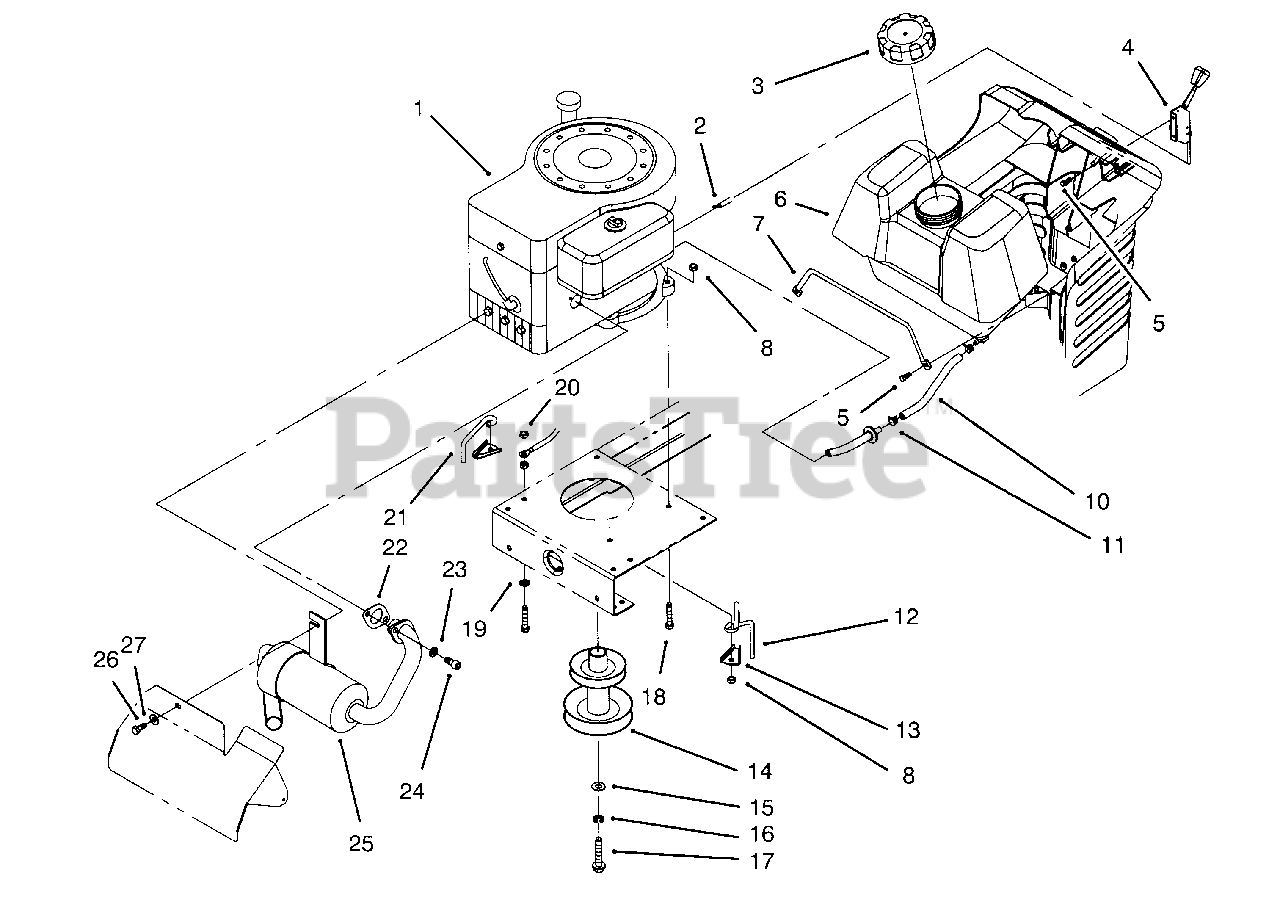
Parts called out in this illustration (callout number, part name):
1	Engine-12 H.P.
2	Cable-Throttle
4	Control-Throttle
5	Screw-Plastite
6	Tank-Gas
7	Rod-Gas Tank
8	Nut-Lock
10	Line-Fuel
11	Clamp-Hose
12	Guide-Belt L.H.
13	Anchor-Belt Guide
14	Pulley-Engine
15	Washer-Flat
16	Washer-Lock
17	Bolt-Blade
18	Screw-Hex Hd. Cap
19	Washer-Ext. Tooth Lock
20	Nut-Keps
21	Guide-Belt R.H.
22	Gasket-Muffler
23	Washer-Lock
24	Screw-Hex Soc. Hd.
26	Screw-Hex Hd. Cap
27	Washer-Lock
